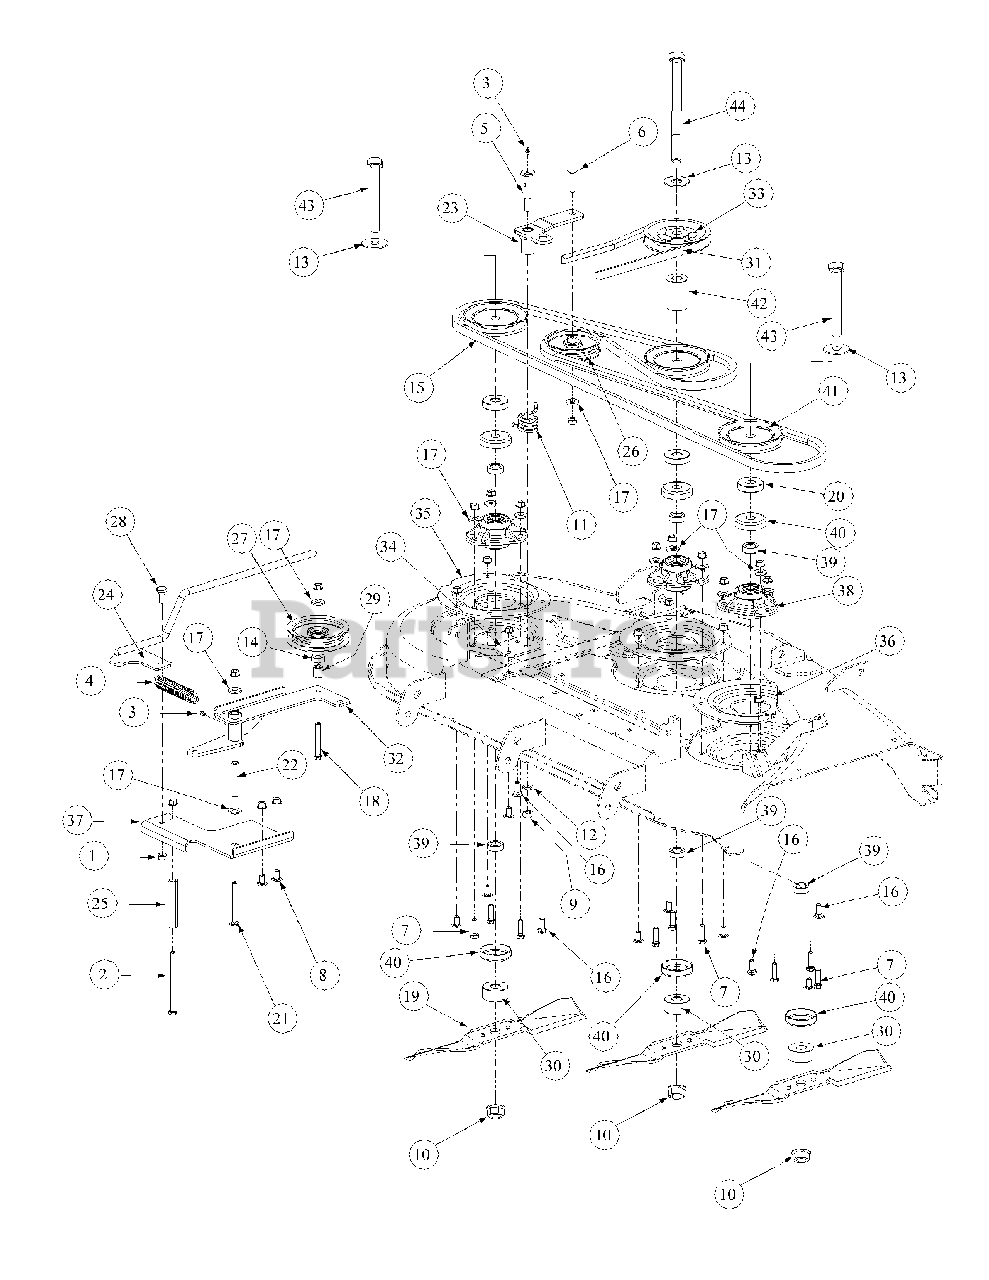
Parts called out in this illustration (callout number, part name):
1	Flange Lock Hex Nut, 3/8-16
2	Hex Capscrew, 3/8-16,5.00
3	Grease Fitting, 1/4-28 x 3/16
4	Extension Spring, 1.0 OD x 5.00
5	Shoulder Screw, 7/16-14
6	Hex Carriage Screw, 3/8-16, 1.75
7	Hex Cap Screw, 3/8-16, 1.25
8	Carriage Bolt, 3/8-16 x .75 Lg
9	Hex Nut, 7/16-14
10	Flange Hex Nut, 3/4-16
11	Torsion Idler Spring
12	Lock Washer, 7/16
13	Flat Washer, .781 ID, 2.00 OD. 105
14	Spacer, .406 ID x 1.00 OD x .38
15	Belt, A Section x 107.3
16	Carriage Bolt, 3/8-16 x 1
17	Flat Washer, .406 ID, 1.0 OD, .105
18	Hex Capscrew, 3/8-16, 2.75
19	Mower Blade, 16.5 Lg
20	Spacer, .76ID x 2.0OD x .477
21	Carriage Bolt, 3/8-16 x 3.5 Lg
22	Spacer, .39 ID x .625 OD x 2.75
23	Idler Arm Assembly, Bearing
24	Idler Spring Rod Assembly
25	Spacer, .405 x .75 x 3.875
26	Flat Pulley with Flanges
27	Idler Pulley, 4.06 OD with Deep Flange
28	Shoulder Screw, .50 x .27 Lg; 3/8-16
29	Spacer, .385 ID x .75 OD x .875
30	Spacer, .760 ID x 2.000 OD x 0.9
31	Belt, B Section x 83.2
32	Idler Arm Assembly, Flat Top Bearing
33	Cast Pulley, 5.25 OD
34	48" Idler Arm Mounting Plate
35	Disk Reinforcement
36	Disk Reinforcement, Right Hand
37	48" Idler Arm Mounting Bracket
38	Bearing Housing Assembly
39	Spacer, .76ID x 1.25 OD x .44 Lg
40	Spindle Cup
41	Pulley, A Sect x 4.90
42	Spacer, .765 ID x 1.75 OD x 2.42
43	Hex Capscrew, 3/4-16, 5.50
44	Hex Capscrew, 3/4-16, 8.50
